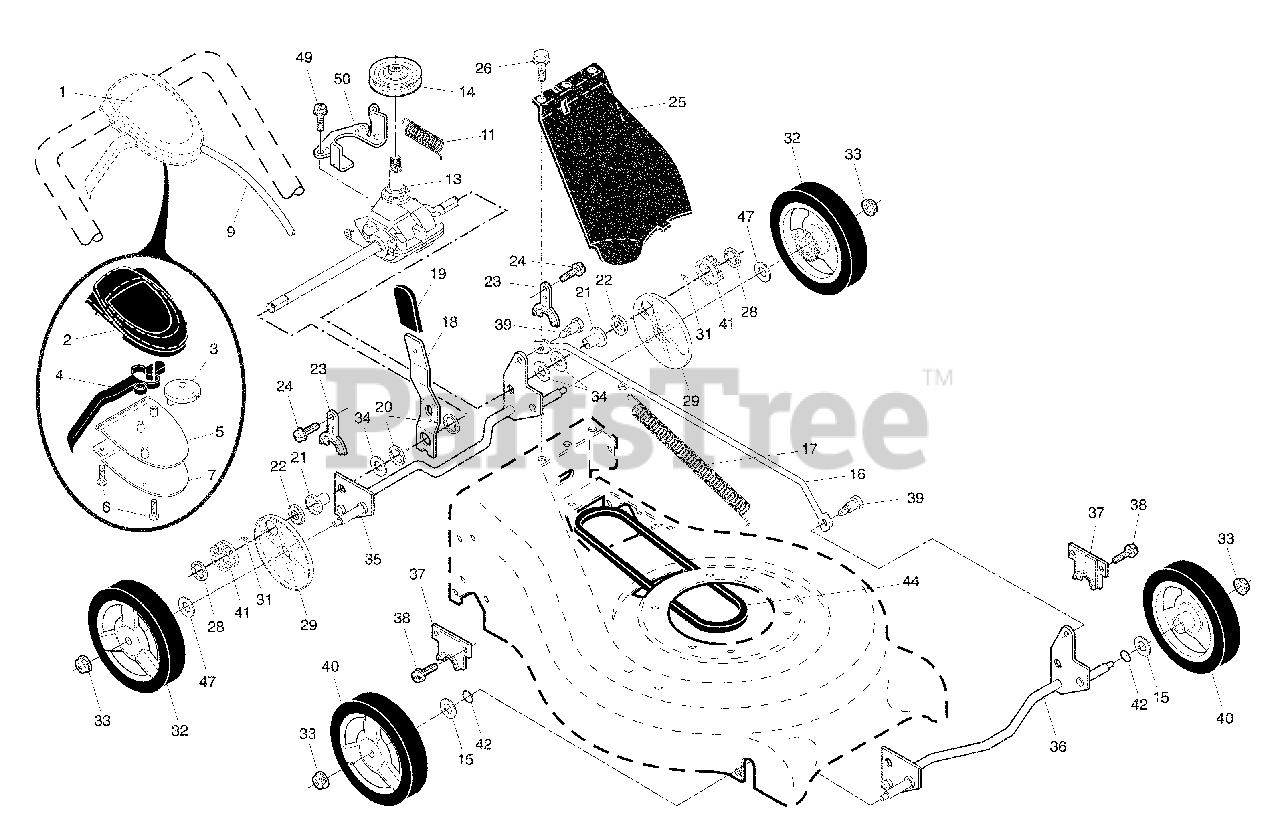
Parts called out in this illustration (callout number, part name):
1	Drive Control Assembly, Auto-Walk
2	Cover, Top, Auto-Walk Drive Control
4	Lever, Auto-Walk Drive Control
5	Cover, Bottom, Auto-Walk Drive Control
6	Screw, Phillips Head #10 x 5/8
7	Plate, Trigger, Auto-Walk Drive Control
9	Cable, Drive Control
11	Spring, Return
13	Gear Case Assembly
14	Pulley, Drive
15	Washer, Flat
16	Rod, Connecting
17	Spring, Extension
18	Spring Selector
19	Knob, Selector Spring
21	Bearing, Support
22	Bearing, Ball
23	Retainer, Drive Assembly, Stamped
24	Screw, Tapping, Hex Head 1/4-20 x 3/4
25	Cover Drive
26	Screw, Threaded, Rolled #10-25 x 1/2
28	E-Ring 7/16
29	Cover, Dust, Wheel
31	Seal, Friction
32	Wheel & Tire Assembly, Rear
33	Nut, Hex, Flangelock 3/8-16
35	Shaft Assembly, Rear
36	Shaft Assembly, Front
37	Retainer, Front Shaft
38	Screw #12 x 5/8
39	Bolt, Shoulder, Semi-Gimlet Point
40	Wheel & Tire Assembly, Front 8 x 1-3/4
47	Washer 1/2 x 1-1/2 x .134
49	Screw, Hi-Lo Thread
50	Belt Keeper
